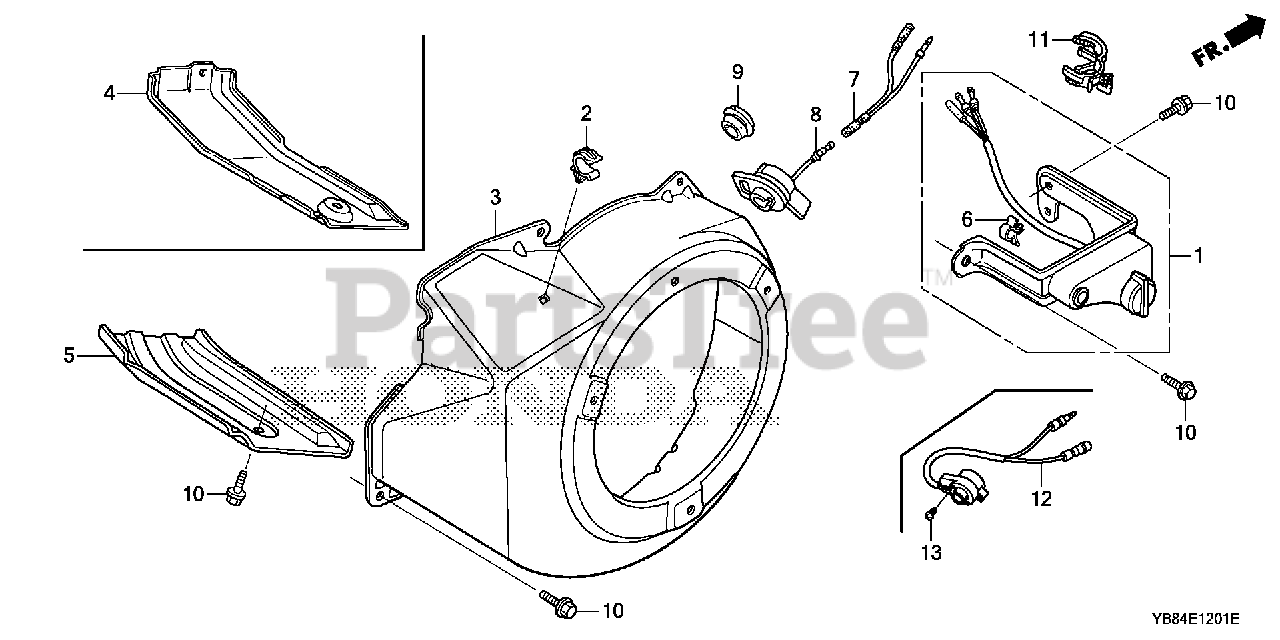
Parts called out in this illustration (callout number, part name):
2	CLIP, TUBE
3	COVER, FAN *R8* (BRIGHT RED)
3	COVER, FAN *R280* (POWER RED)
7	SUB-HARNESS
8	SWITCH ASSY., ENGINE STOP
10	BOLT, FLANGE (6X12) (CT200)
11	CLIP, HARNESS
